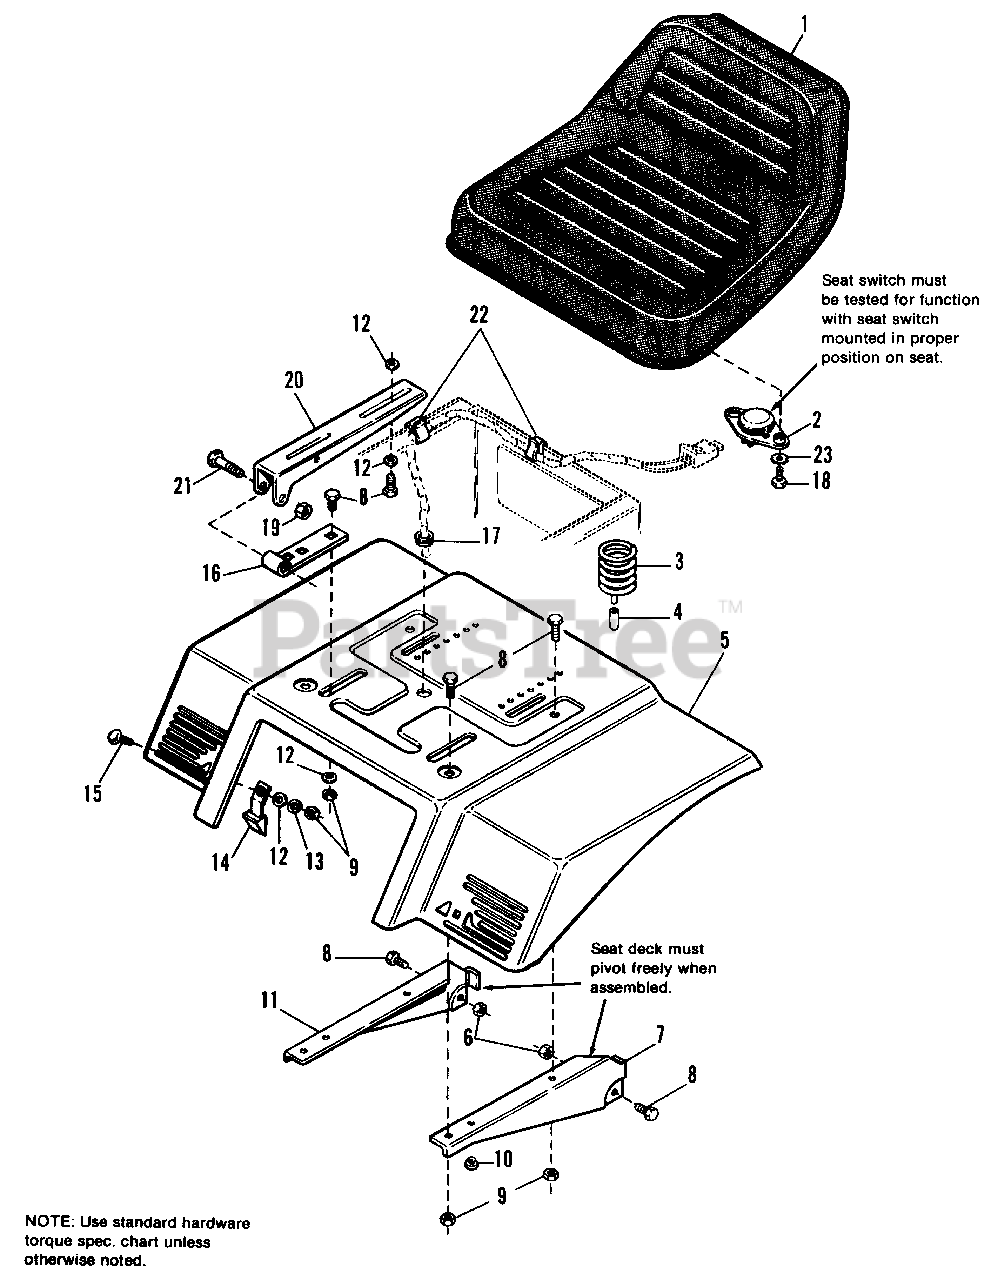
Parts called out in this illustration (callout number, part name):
2	SWITCH, Seat
3	SPRING, Seat
4	COVER, Wire
5	DECK, Seat
6	NUT, Lock, Hex, 5/16-18
7	SUPPORT, Seat. L.H.
8	CAPSCREW, Hex Hd., 5/16-18 x 3/4
9	NUT, Hex, 5/16-18
10	BUMPER, Plug
11	SUPPORT, Seat, R.H.
12	WASHER, 5/16
13	LOCKWASHER, 5/16
14	SEAT LATCH ASSY.
15	BOLT, Carriage, 5/16-18 x 3/4
16	HINGE, Lower
17	BUSHING, Snap
18	SCREW, Rd. Hd., 1/4-20 x 3/4
19	NUT, Hex Lock, 3/8-16
20	HINGE, Upper
21	CAPSCREW, Hex Hd., 3/8-16 x 2
23	LOCKWASHER, Ext. Tooth, 1/4
